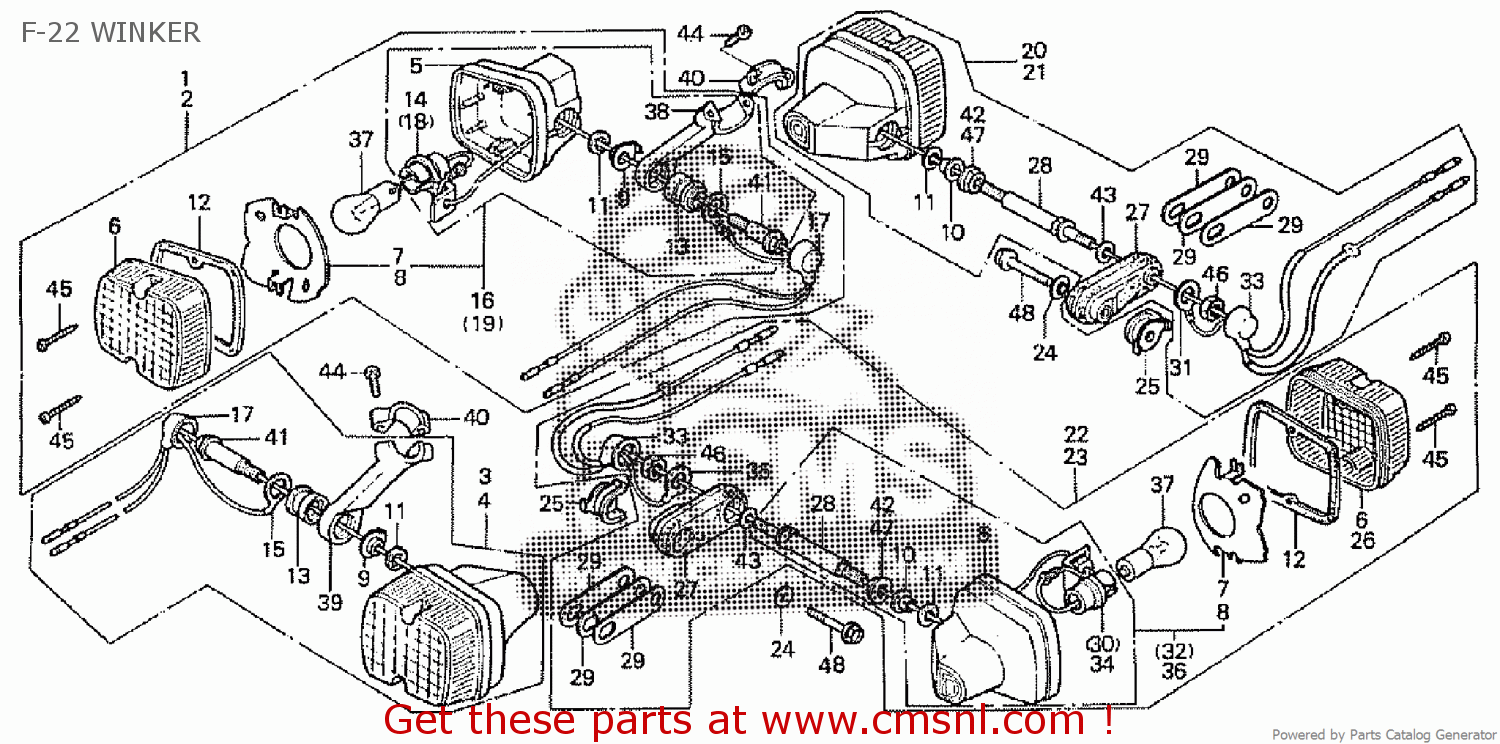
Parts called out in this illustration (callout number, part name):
1	WINKER SET,R.FR.
2	WINKER SET,R.FR.
3	WINKER SET,L.FR.
4	WINKER SET,L.FR.
5	BASE,WINKER
6	LENS,WINKER
7	REFLECTOR
8	REFLECTOR
9	STOPPER, FR.
10	COLLAR,WINKERBASE
11	SEAL,GASKET
12	LENS,GASKET
13	RUB,FR.WINKER MT.
14	SOCKET R WINKER
15	CORD,WINKER EARTH
16	BASE,R.FR.WINKER
17	COVER,WINKER CORD
18	SOCKET L WINKER
19	BASE,L.FR.WINKER
20	WINKER SET,R.RR.
21	WINKER SET,R.RR.
22	WINKER SET,L.RR.
23	WINKER SET,L.RR.
24	WASHER,RR.WINKER
25	STAY RR WINKER
26	LENS,WINKER
27	RUB RR WINKER
28	BOLT,RR.WINKER
29	SPRING,RR.WINKER
30	SOCKET R RR
31	CORD WINKER EARTH
32	BASE,R.RR.WINKER
33	COVER,WINKER CORD
34	SOCKET L RR
35	CORD WINKER EARTH
36	BASE,L.RR.WINKER
37	BULB,WINKER
38	BRKT R FR WINKER
39	BRKT L FR WINKER
40	HOLD,WINKER STAY
41	BOLT,WINKER SET
42	NUT,HEX.,10MM
43	WASHER (10.2X20)
44	SCREW,CROSS,5X16
45	SCREW,TAPPING4X25
46	NUT,HEX.,10MM
47	NUT,FLANGE,10MM
48	BOLT,FLANGE,6X50
